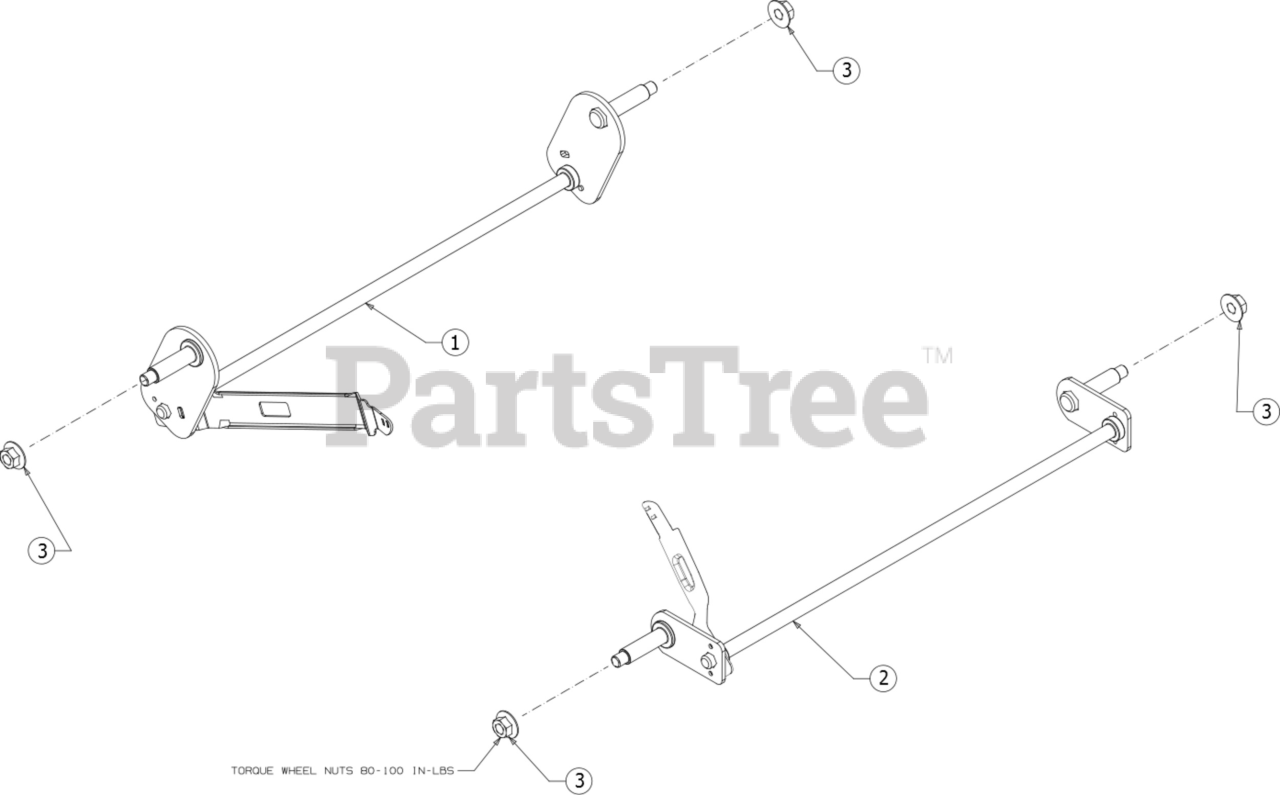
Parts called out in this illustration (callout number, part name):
1	11" REAR AXLE ASSEMBLY
2	7" FRONT AXLE ASSEMBLY
3	FLANGE LOCK NUT
